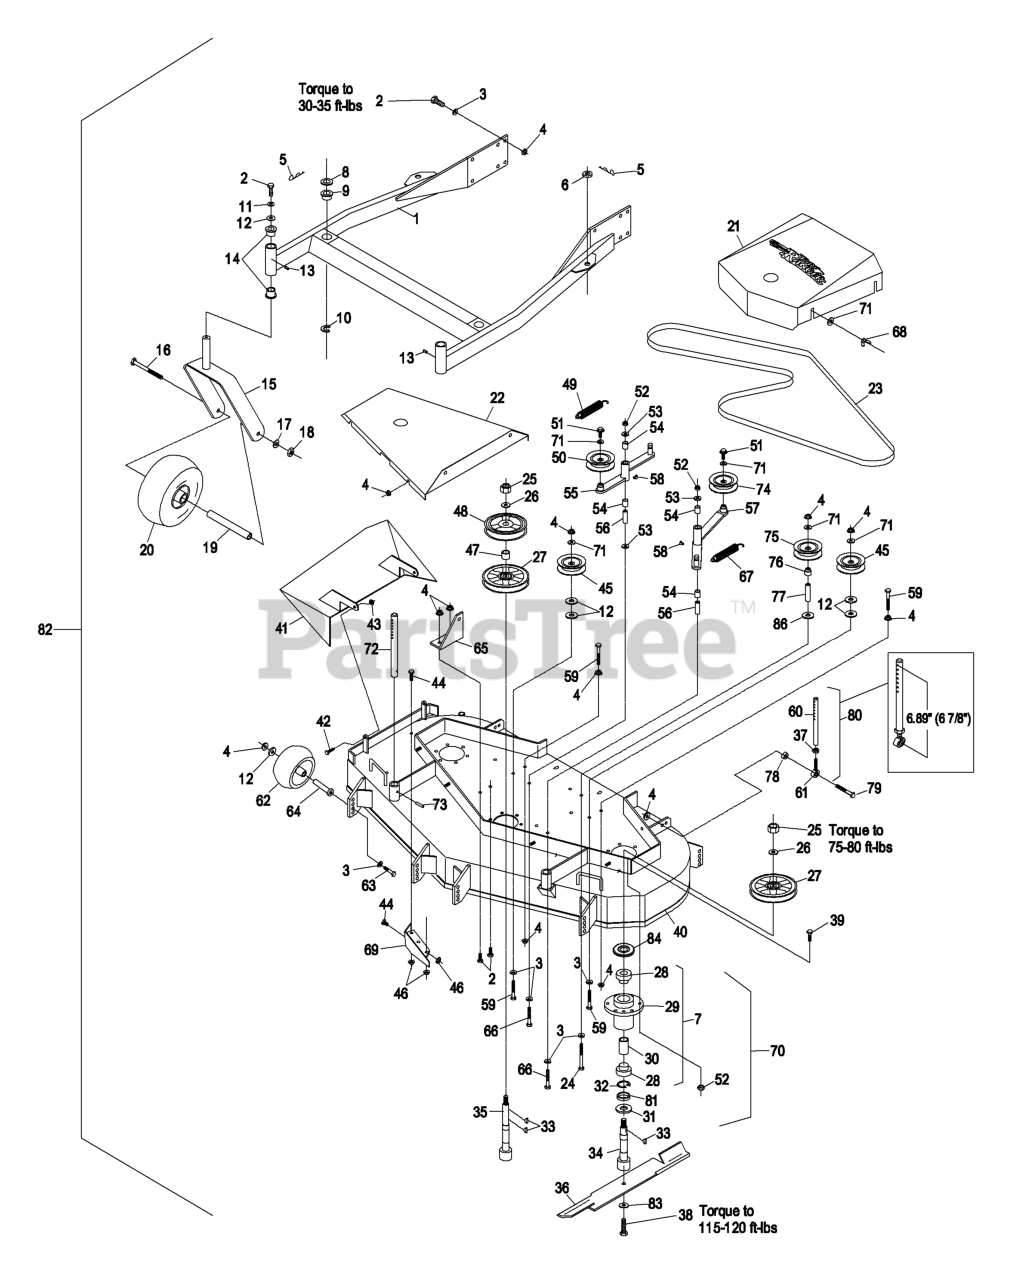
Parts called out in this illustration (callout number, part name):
2	SCREW-HH
3	WASHER-BELLEVILLE
4	NUT-HHF, WHIZ
5	PIN,HAIR COTTER
8	SPACER-DECK SUPPORT
9	BUSHING-DECK
10	RING-RETAINING
11	WASHER-LOCK
12	WASHER
13	FITTING-GREASE
14	BEARING-FLANGED
16	SCREW-HH
17	WASHER-LOCK
18	NUT-HH
21	COVER W/DECAL TR/FMD523
23	BELT,BLADE DRIVE
24	SCREW-HH
25	NUT-HEX
26	WASHER-SPRING
27	SHEAVE,BLADE DRIVE
28	BEARING
30	SPACER-BEARING
31	GUARD-BEARING, BOTTOM
32	RING-SNAP
33	KEY-WOODRUFF
34	SHAFT,SPINDLE SHORT
37	NUT-HEX
38	SCREW-CAP
39	SCREW-HH
41	WLD,CHUTE DISCHARGE
42	SCREW-HH
43	NUT-LOCK, NI
44	SCREW-HH
45	IDLER,PULLEY
47	SPACER-TUBE
48	SHEAVE,MOWER DRIVE
49	SPRING-EXTENSION
50	IDLER,PULLEY
51	Screw, Whizlock 3/8-16 X 1
52	NUT-LOCK, NI
53	WASHER-FLAT
54	SLEEVE-BEARING
55	ASM,IDLER ARM
56	BUSHING-PIVOT, IDLER
57	ASM,IDLER ARM
58	FITTING-GREASE, 90 DEG
59	SCREW-HH
60	LINK,SUPPORT
61	BALLJOINT
62	ROLLER-SCALP, ANTI
63	SCREW-HH
64	BUSHING-ROLLER
65	BRACKET,SPRING ANCHOR
66	SCREW-HH
67	SPRING-EXTENSION
68	NUT-WING
69	WLD,BAFFLE DISCHARGE
70	ASM,CUTTER HSG SERVICE
71	WASHER-FLAT
72	ROD,DECK SUPPORT
74	PULLEY-IDLER
75	PULLEY-IDLER
76	BUSHING,IDLER
77	SPACER-FENDER
79	SCREW-HH
81	SPACER-PULLEY/BEARING
82	Asm,Complete Deck
83	WASHER-BLADE BOLT, HEAVY
84	GUARD,BEARING TOP .880
85	KIT, SP CASTER WHEEL REPL
86	WASHER
